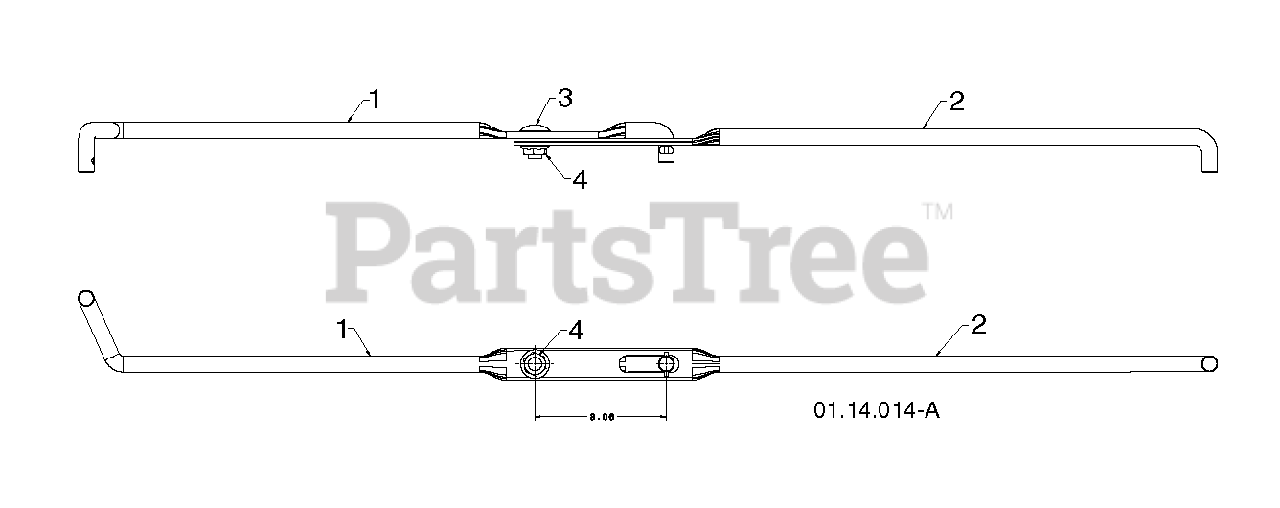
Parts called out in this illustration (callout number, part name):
1	ROD.SHIFTER.TOP.HYD.SNOW
2	ROD, LOWER, SPEED CONTROL
3	BOLT
4	NUT.FLANGE.5/16
